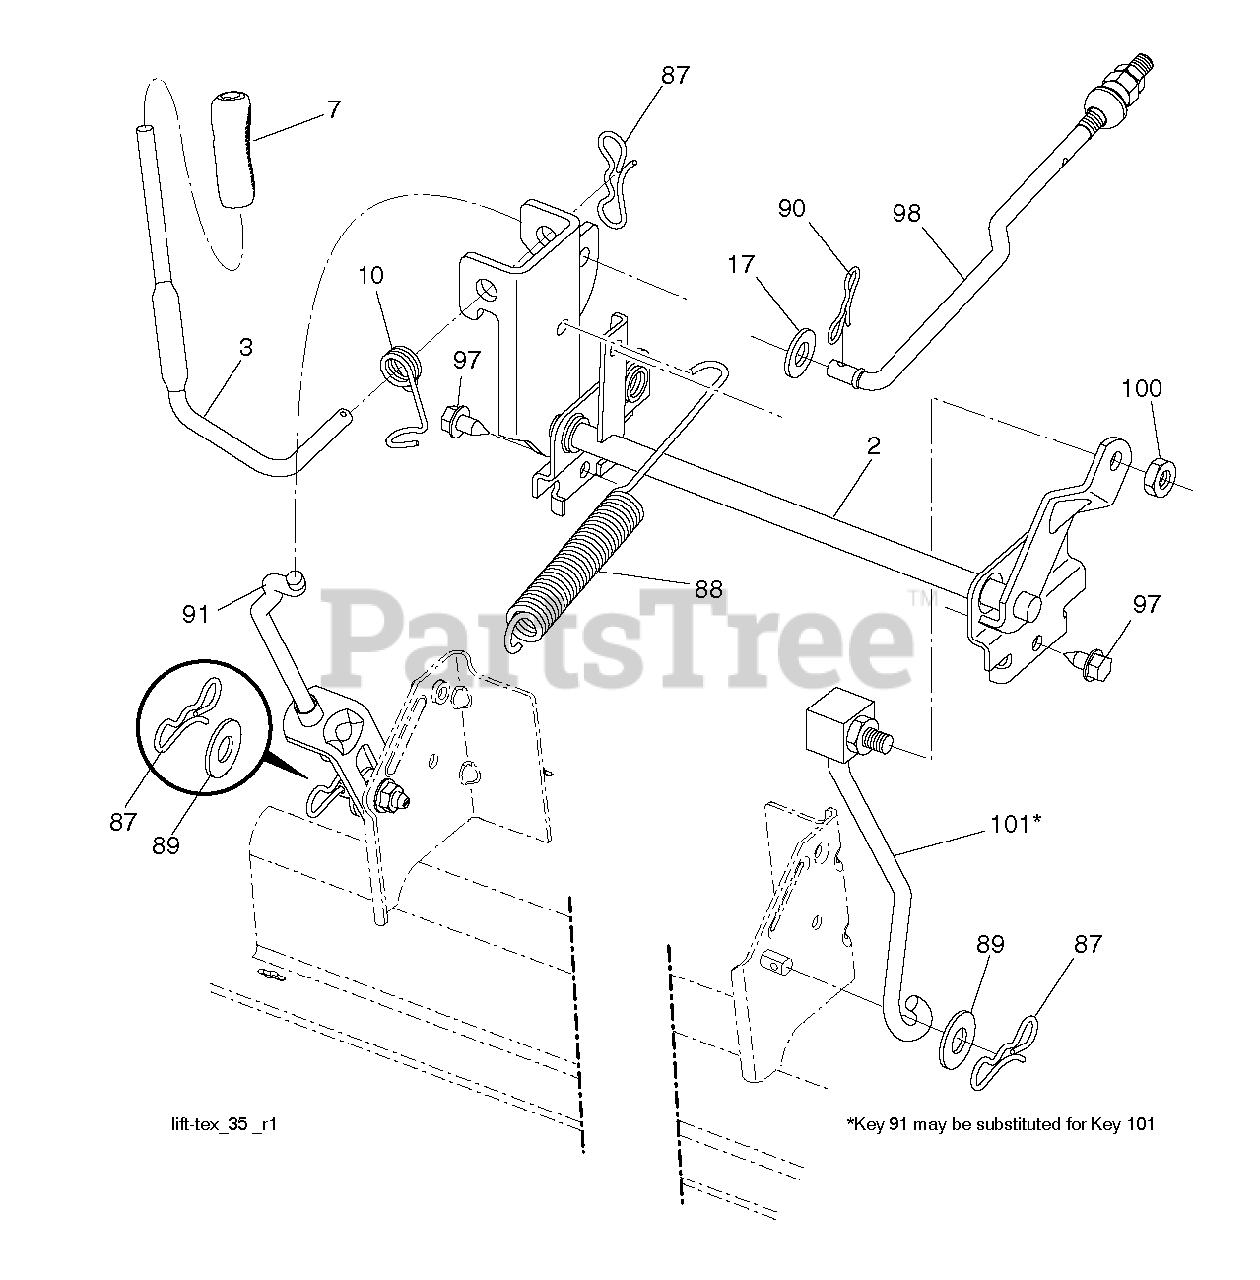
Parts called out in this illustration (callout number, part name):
2	SHAFT.ASM.CROSS.LIFT
3	LEVER.LIFT.HANDLE.LT
7	GRIP.HANDLE.LIFT.PVC.BLACK
10	SPRING.TORSION.LIFT.HANDLE
17	WASHER
87	PIN.COTTER.7/16.BOW TI.
88	SPRING.LIFT.ASSIST
89	WASHER.CLEAR.ZINC
90	PIN.COTTER.5/16.BOW TI
91	LINK.ASM.LIFT.REAR
97	SCREW, 3/8-16X3/4
98	LINK.ASM.SUSP.FRONT.MW
100	LOCKNUT
101	LINK.ASM.LIFT.FIXE.38/42/46"
